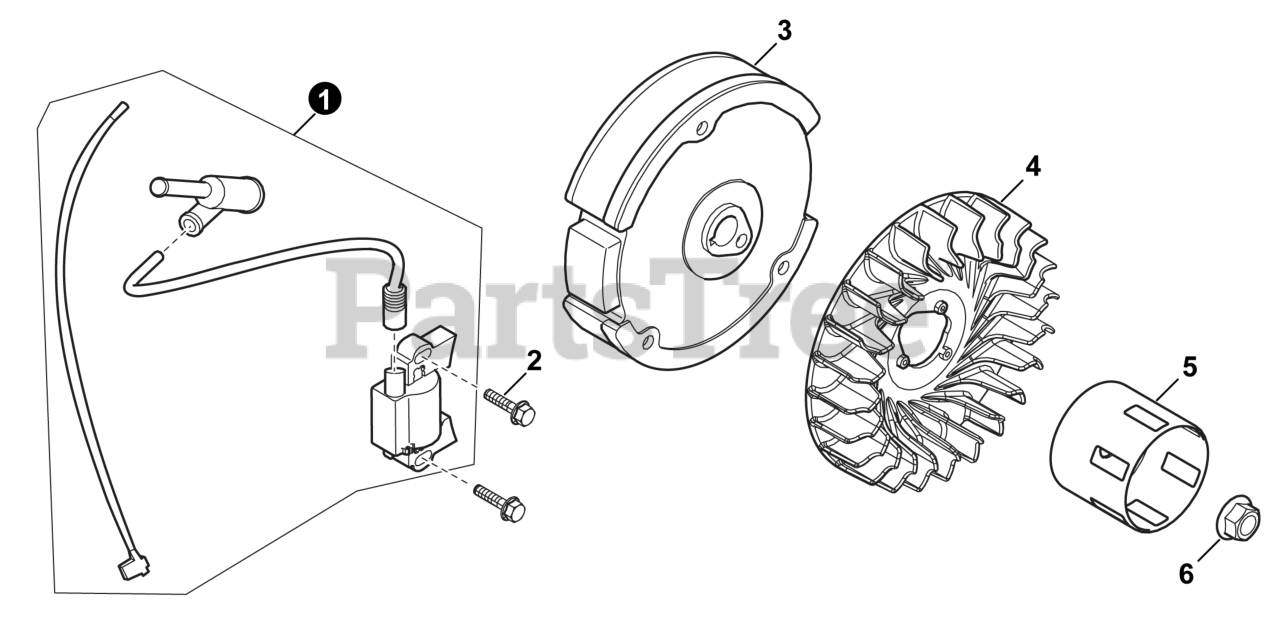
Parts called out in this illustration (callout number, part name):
1	COIL, IGNITION
3	FLYWHEEL
4	IMPELLER
5	PULLEY,STARTER
6	NUT, FLYWHEEL
